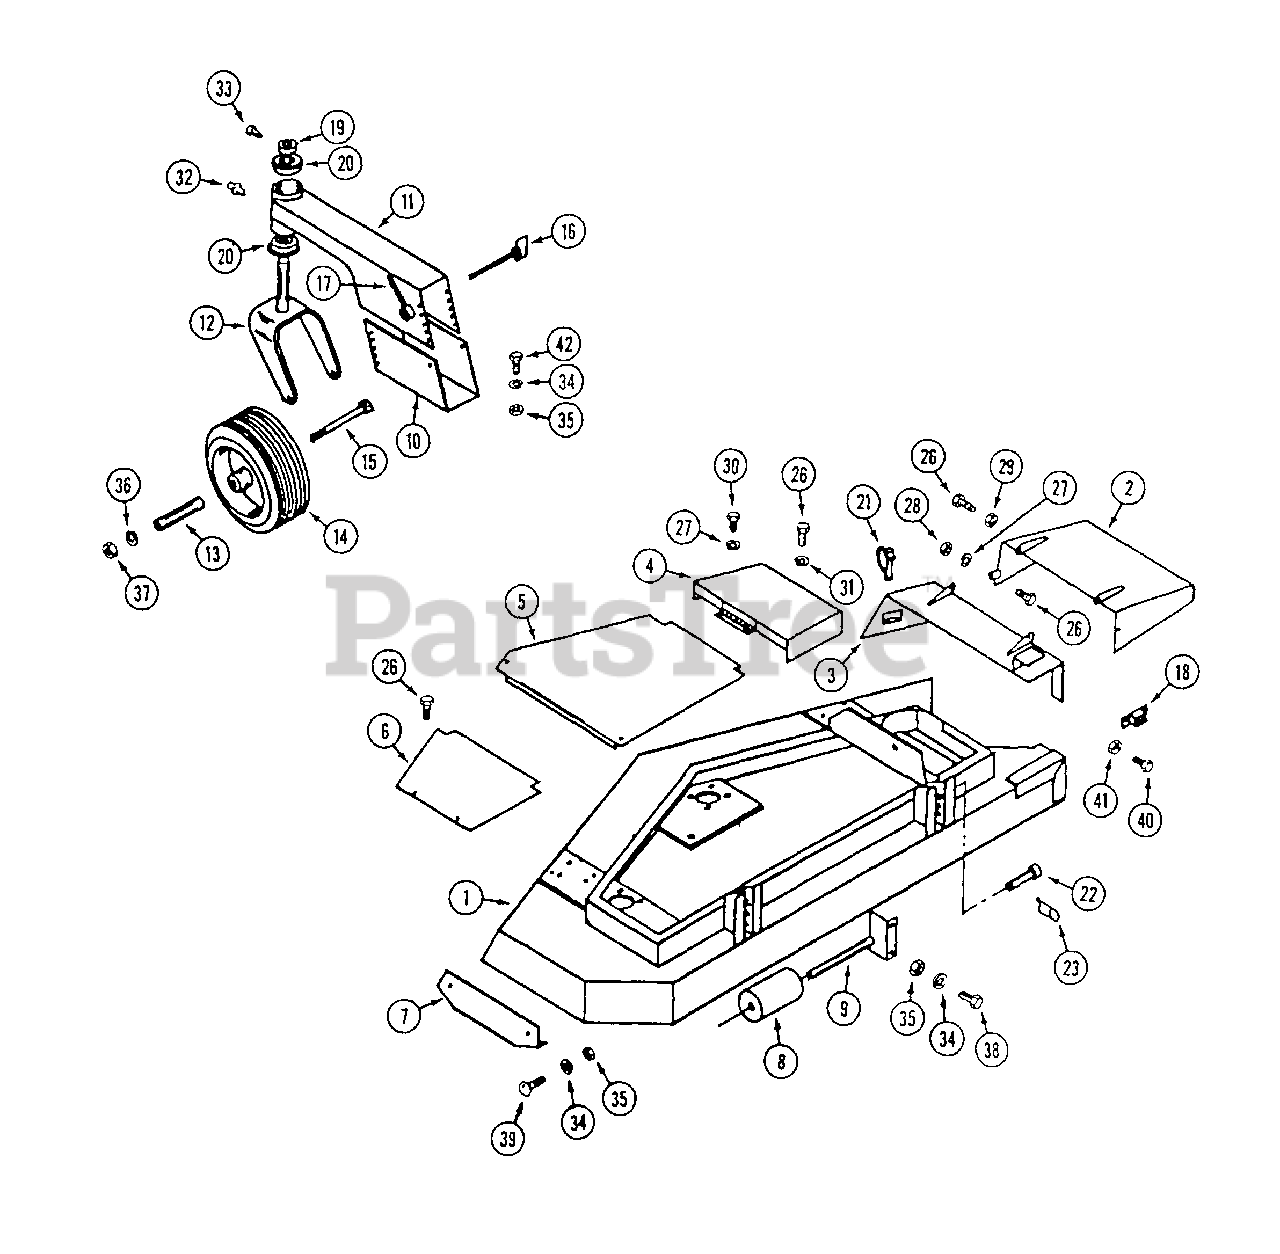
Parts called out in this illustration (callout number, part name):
2	CHUTE - foot guard
3	MOUNT - foot guard
4	COVER - pulley
5	COVER - center
8	ROLLER - anti-scalp
9	SHAFT - roller
10	BRACKET - gauge wheel mount
11	MOUNT - gauge wheel
13	AXLE - wheel
15	BOLT - 1/2" - 13 x 6-1/2"
17	NUT - gauge wheel handle
18	BREAKER - circuit, 10 amp.
21	PIN - "fas-tatch"
23	PIN - cotter, hair
26	BOLT - 1/4" - 20 x 3/4"
27	LOCKWASHER - 1/4"
28	NUT - 1/4" - 20
29	NUT - 1/4" - 20 lock
30	BOLT - 1/4" - 20 x 1"
31	WASHER - 1/4"
32	FITTING - grease
33	SCREW - set 5/16" - 18 x 1/2" square head
34	LOCKWASHER - 5/16"
35	NUT - 5/16" - 18
36	LOCKWASHER - 1/2"
37	NUT - 1/2" - 13
39	BOLT - 5/16" - 18 x 3/4" carriage
40	SCREW - #10 - 32 x 1/2"
41	NUT - #10 - 32
42	BOLT - 5/16" - 18 x 1" carriage
